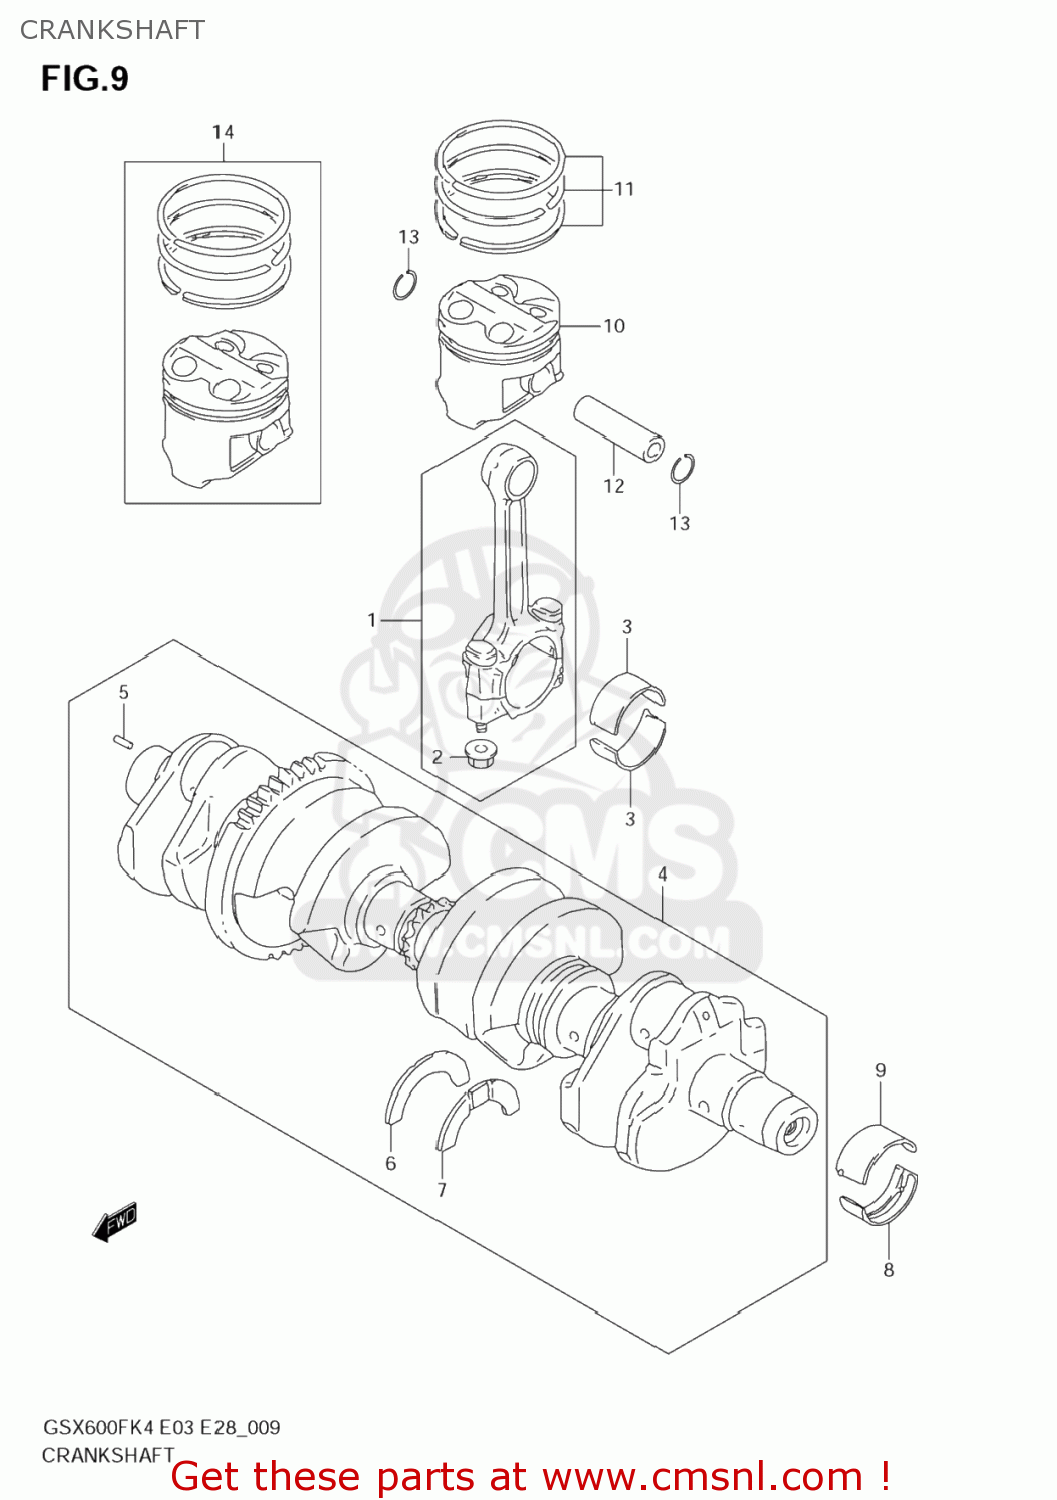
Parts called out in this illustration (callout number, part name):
1	CONNECTING ROD ASSY
2	NUT
3	BEARING,CRANK PIN
4	CRANKSHAFT SET
5	PIN
6	PLATE,CRANK THRUST
7	PLATE,CRANK THRUST
8	BEARING,CRANKSHAFT LWR
9	BEARING,CRANKSHAFT UPR
10	PISTON
11	RING SET,PISTON
12	PIN,PISTON
13	CIRCLIP
14	PISTON SET(OS:0.5)
